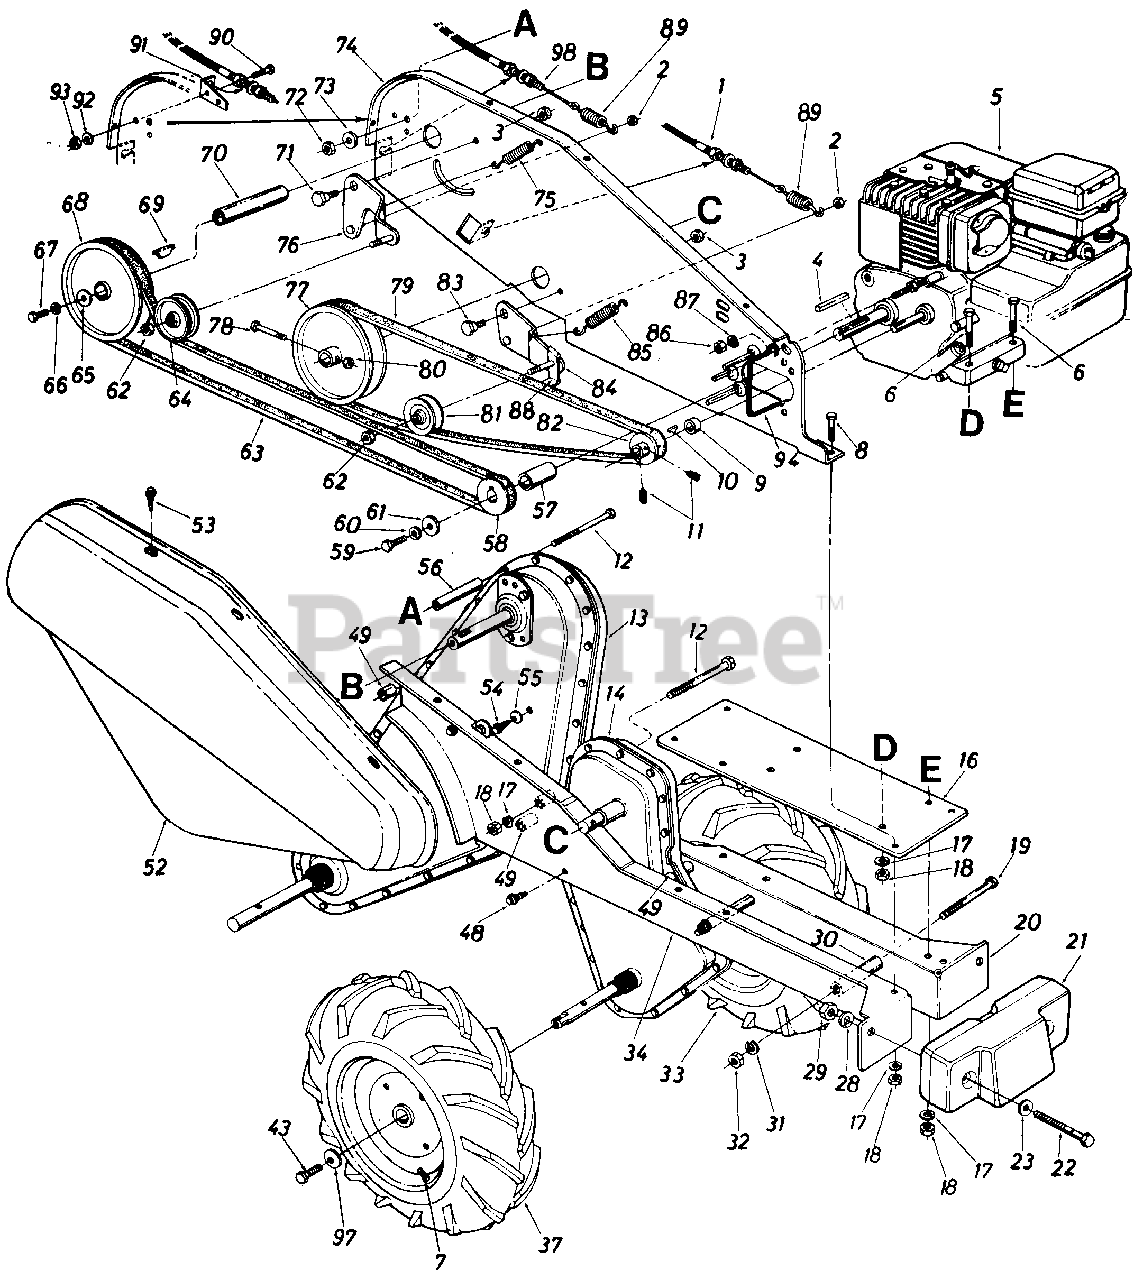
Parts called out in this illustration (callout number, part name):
1	Clutch Control Cable (Wheels)
2	Hex Cent. L-Nut 1/4-20 Thd.
3	Hex Cent. L-Nut 3/8-16 Thd.
4	Sq. Key 3116" Dia. x .75
5	Engine
6	Hex Bolt 5/16-18 x 1.50" Lg.
7	Air Valve
8	Hex Bolt 5/16-18 x .75" Lg.
9	Spacer .51" I.D. x 314" O.D. x.39" Lg.
10	Hi-Pro Key #5 Woodruff
11	Set Scr. '/4-28 x .25" Lg.
12	Hex Bolt 5/16-18 x 3.0" Lg.
16	Engine Mounting Plate
17	L-Wash. 5/16" I.D.*
18	Hex Nut 5/16-18 Thd.
19	Hex Bolt 3/8-24 x 3.0" Lg.
22	Hex Bolt 1/2-13 x 4.0" Lg.*
23	Fl-Wash. 1/2" I.D. x 1.0" O.D.
28	L-Wash. 1/2" I.D.
29	Hex Nut 1/2-13 Thd.*
30	Spacer 318" I.D. x 518" O.D. x2.18" Lg.
31	L-Wash. 318" I.D.*
32	Hex Nut 3/8-24 Thd.*
33	Comp. Wheel Ass'y.-L.H.
33	Rim Ass'y.
33	Tire Only
37	Rim Ass'y.
37	Tire Only
43	Hex Bolt 5/16-24 x .62" Lg.
48	Hex Wash. Self-Tap Scr. 5/16-24 x .50" Lg.
49	Spacer 5116" I.D. x 16 Ga. x.96" Lg.
54	Hex Wash. S-Tap Scr. 1/4-20 x 318" Lg.
55	Bell-Wash. 1/4" I.D.
56	Spacer 3/8" I.D. x 1/2" O.D. x 2.0" Lg.
57	Spacer 3/4" I.D. x 1.12" O.D. x 1.56" Lg.
58	1/2" "V"-4L Pulley 3/4" I.D. x 2.59" O.D.
59	Hex Bolt 5/16-24 x 1.0" Lg.
60	L-Wash. 5/16" I.D.*
61	Fl-Wash. 5/16" I.D. x 1.25" O.D.
62	Hex L-Nut 3/8-24 Thd.
63	V-Belt
64	Fl-ldler Pulley 3.75" O.D. x 3/8" I.D.
65	Fl-Wash. .25" I.D. x .93" O.D. x .120
66	L-Wash. 1/4" I.D.
67	Hex Bolt 1/4-28 x .75" Lg.*
68	Split Pulley 6" Dia. x 5/8" I.D.
69	Hi-Pro Key
70	Spacer
71	Shld. Bolt 1/2" Dia. x .210" Lg.
72	Hex Nut 5/16-18 Thd.
73	L-Wash. 5/16" I.D.
74	Side Plate Ass'y.
75	Ext. Spring .50" O.D. x 1.55" Lg.
76	Idler Bracket Ass'y.-Tines
77	Pulley 6" Dia. x 518" I.D.
78	Hex Bolt 1/4-28 x 1.50" Lg.
79	V-Belt
80	Hex Cent. L-Nut 1/4-28 Thd.
81	V-ldler Pulley 2-5/8" O.D.
82	1/2" "V"-Pulley 21/4" O.D. x .50" I.D.
83	Shld. Bolt 1/2" Dia. x .160" Lg.
84	Idler Bracket Ass'y-Wheels
85	Ext. Spring .50" O.D. x 1.55" Lg.
86	Hex Nut 1/4-20 Thd.
87	Bell-Wash. 1/4" I.D.
88	Belt Keeper Ass'y.
89	Ext. Spring
90	Hex Bolt 5/16-18 x .75"*
91	Clutch Cable Brkt.
92	Lock Washer 5/16" l.D.
93	Hex Nut 5/16-18 Thd.
94	Belt Keeper
97	Bell-Wash. 5/16" I.D.
98	Clutch Control Cable (Tines)
